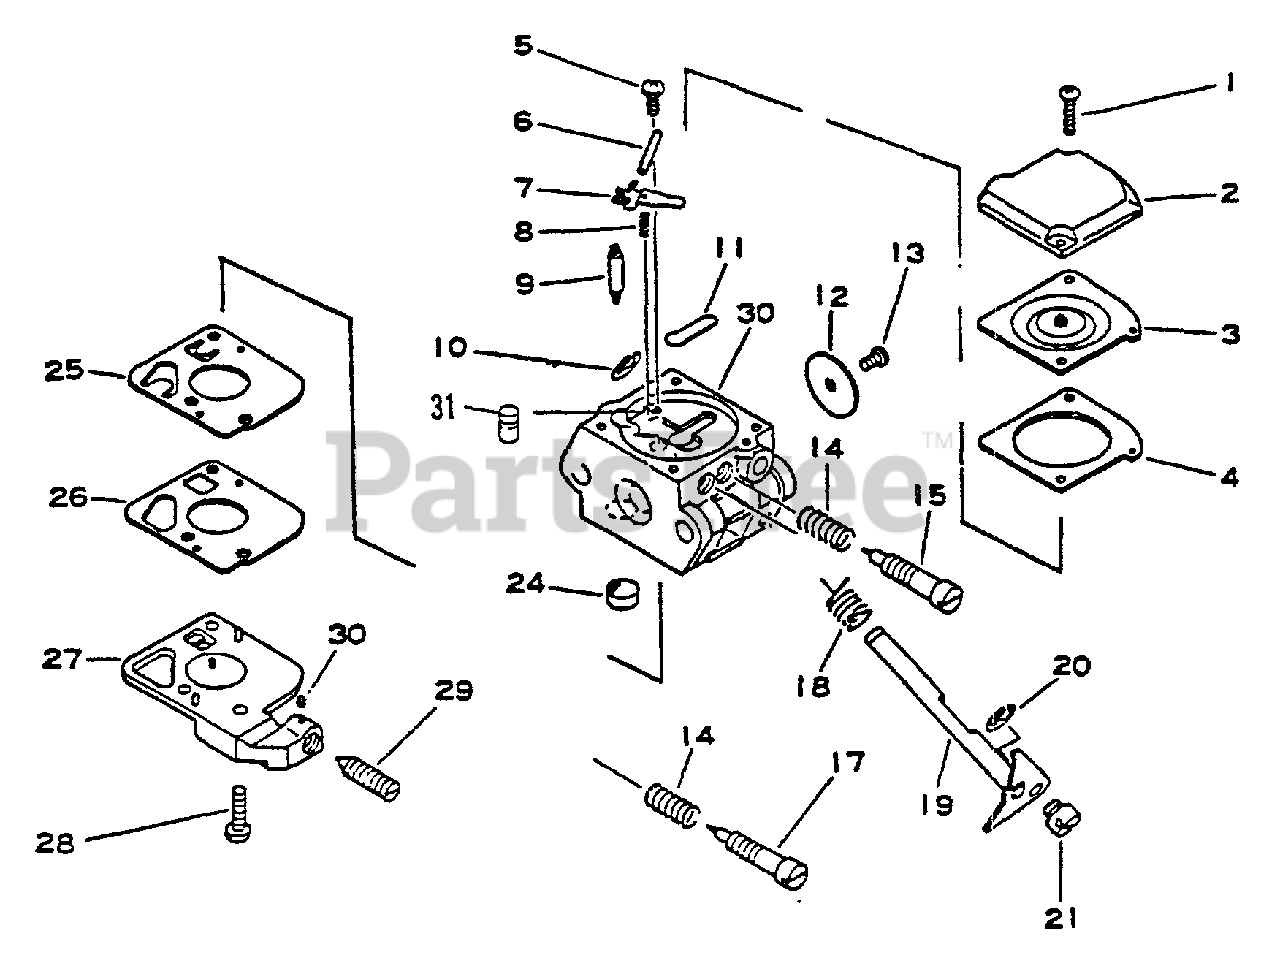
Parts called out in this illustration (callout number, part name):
2	COVER, METERING
3	DIAPHRAGM
4	GASKET, METERING
5	SCREW, METERING LEVER PIN
6	PIN, METERING LEVER
7	LEVER, METERING
8	SPRING
9	NEEDLE, INLET
10	RING, RETAINING
11	PLUG, WELCH
12	VALVE, THROTTLE
15	NEEDLE - HIGH SPEED
17	NEEDLE - MIXTURE
18	SPRING, RETURN
19	SHAFT, THROTTLE
20	RING, RETAINING
24	STRAINER
25	DIAPHRAGM, PURGE
26	GASKET, PURGE
27	BASE, PURGE
28	SCREW, PUMP COVER
29	SCREW, IDLE ADJUST
30	PIECE, FRICTION
31	NOZZLE, CHECK VALVE
